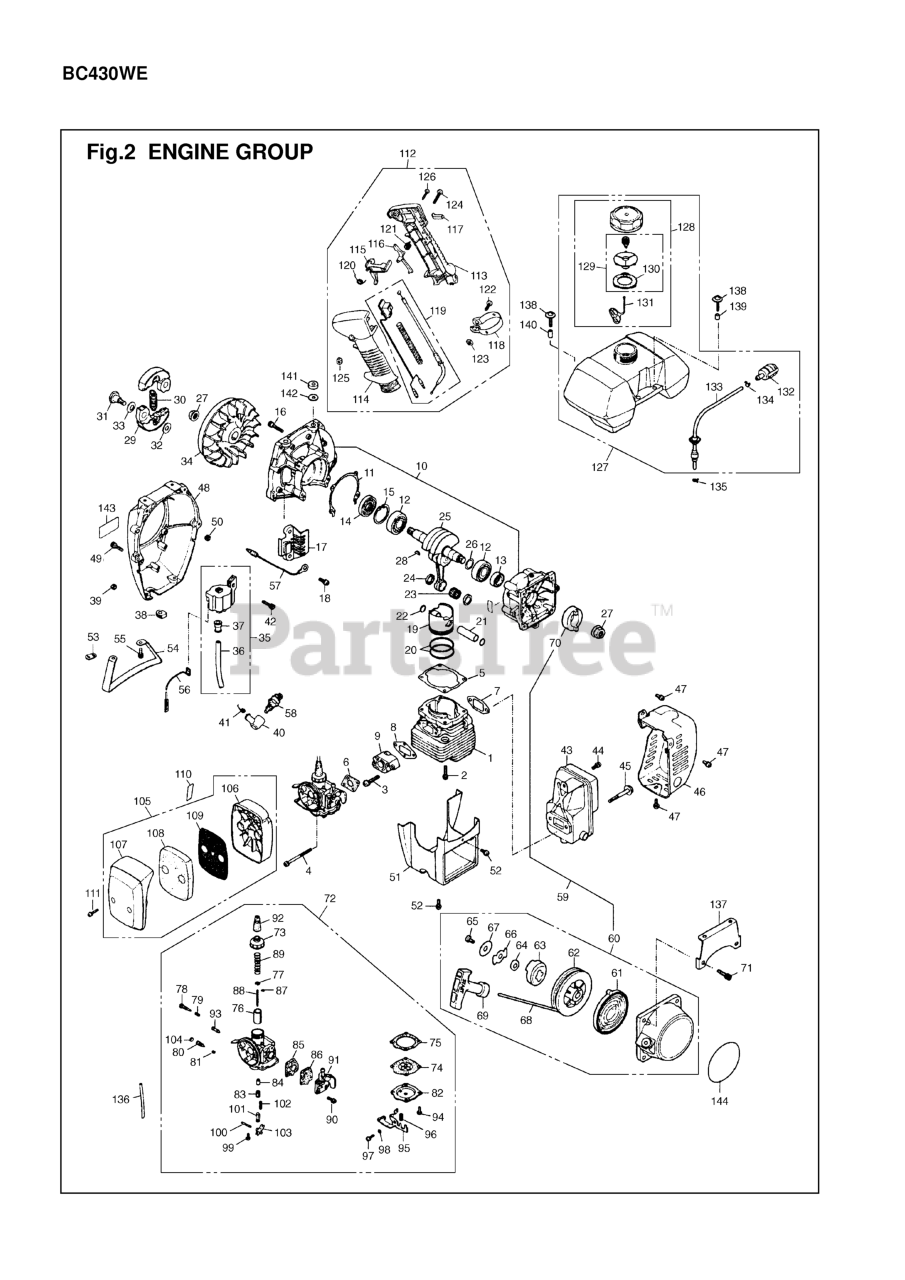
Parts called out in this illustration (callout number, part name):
1	CYLINDER (RPLS -12112)
2	BOLT
9	INSULATOR
10	CRANKCASE COMPLETE
13	SEAL, OIL - STARTER SIDE
15	RING, SNAP, M35 X 1.5
16	BOLT, M5 X 30
17	GUARD (RPLS-21310)
19	PISTON (NLA)
20	RING, PISTON (RPLS -41210)
21	PIN, PISTON
22	RING
23	BEARING
24	WASHER
25	SHAFT (RPLS -42001)
26	SHIM
27	NUT
28	KEY
29	SHOE (RPLS -51112)
31	SCREW
32	WASHER
33	WASHER (USE -51241)
36	CORD, HIGH TENSION
37	CAP
38	GROMMET
41	SPRING
45	BOLT
48	COVER, FAN (REPLACES -31111)
49	BOLT
51	CYLINDER COVER
55	BOLT
57	EARTH CORD
61	SPRING
63	DOG
64	WASHER
65	SCREW
66	RETAINER
67	WASHER
68	ROPE
69	KNOB
70	PULLEY
72	CARBURETOR ASSY
73	CAP (RPLS -81121)
74	DIAPHRAGM ASSEMBLY (NLA)
75	PACKING
76	VALVE, THROTTLE
77	RECEIVER
79	SPRING, ADJUST
80	SCREW (REPLACES 1420-81270)
81	SPRING, MJ,ADJ
82	COVER, DIAPHRAM
83	HOLDER, NEEDLE
84	JET, NEEDLE
85	PACKING, PUMP
86	DIAPHRAGM
87	CLIP (USE 1030-81000-16)
91	COVER ASS
95	LEVER, TICKLER
96	SPRING, TACKLE
101	VALVE NEEDLE
102	SPRING, HINGE
103	HINGE, VALVE
106	BODY (RPLS -82111)
108	ELEMENT (REPLACES 1400-82130)
109	SCREEN
110	LABEL
115	LEVER
116	LEVER
118	BAND
119	CABLE COMP
120	SPRING
121	SPRING
123	NUT
125	NUT
126	SCREW
127	TANK ASSY
128	CAP ASSY
129	VALVE COMP
130	PACKING (RPLS -85321)
131	STOPPER (RPLS 3317-57240)
132	FILTER ASSY (W/CHECK VALVE)
133	PIPE, FUEL (W/ PRIMARY PUMP)
134	CLIP
137	SUPPORT (RPLS -86213)
138	SCREW, M5 X 22
142	WASHER (USE 181741)
